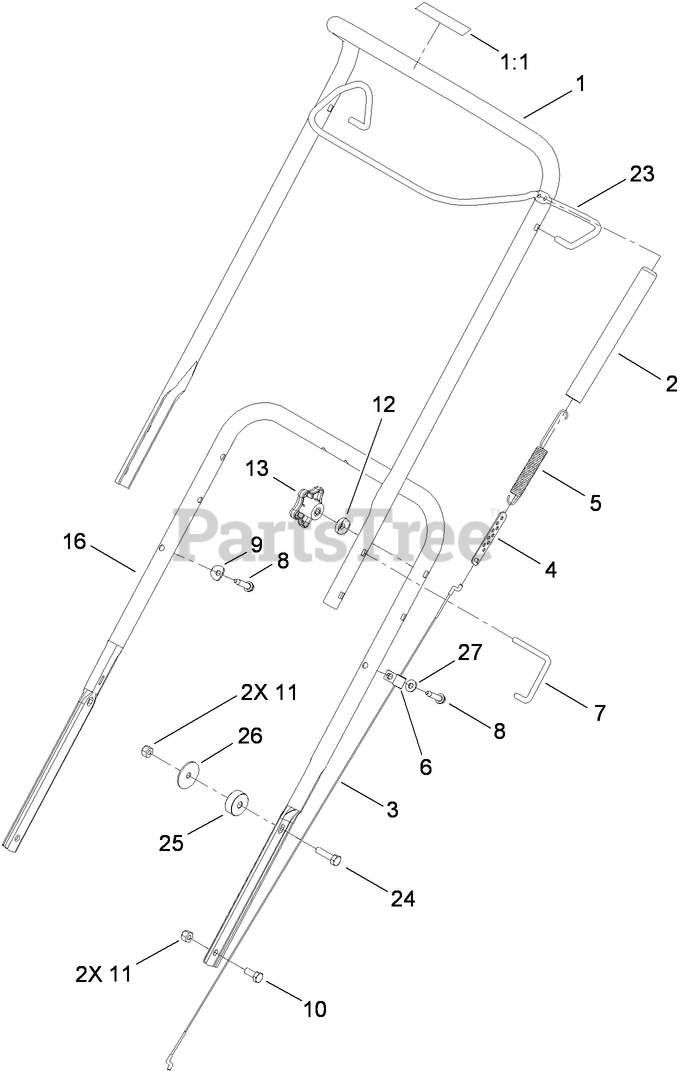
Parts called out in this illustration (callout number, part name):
1	UPPER HANDLE ASM
1:1	DECAL-DRIVE, ROTOR
2	COVER-SPRING
3	CABLE-CLUTCH
5	SPRING-EXTENSION
6	CLAMP
7	LOCK-HANDLE
8	SCREW-HWH
9	WASHER
10	SCREW-HH
11	NUT-LOCK, NI
12	WASHER
13	KNOB-HANDLE
16	HANDLE-LOWER
23	BAIL-CONTROL
24	SCREW-HH
25	SPACER
26	WASHER-FLAT
27	WASHER-FLAT
